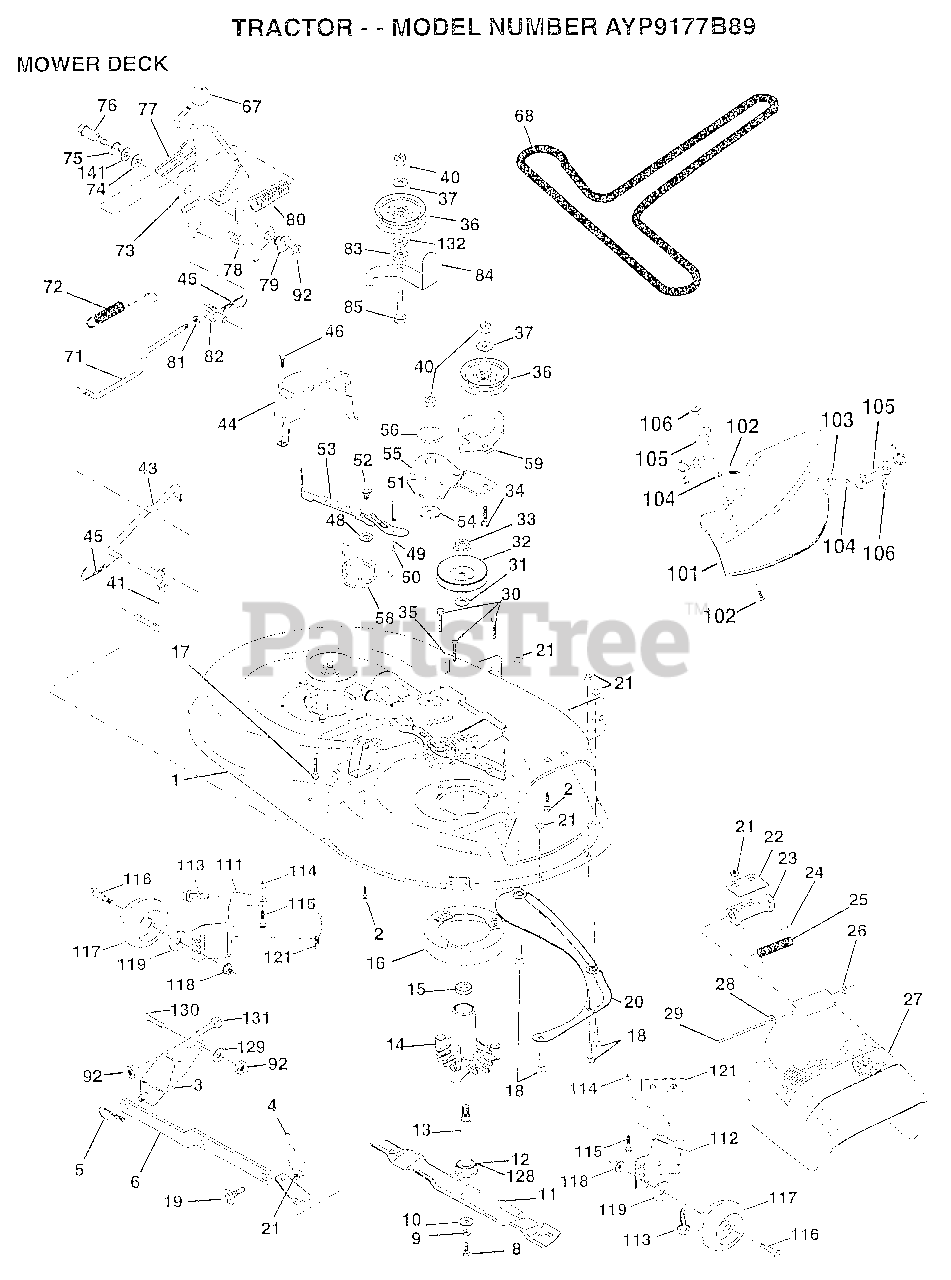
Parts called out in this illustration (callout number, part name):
1	"HOUSING ASSY.42"""
2	BOLT
3	BRKT ASM SWAY BAR
4	BRKT DECK SW BAR
8	BLADE BOLT
10	WASHER.HARD.BLADE
11	"BLADE.42"" MULCHER"
12	BEARING.BALL
14	HSG ASM MANDREL
15	BEARING
16	STRIPPER RND MWR
17	BOLT RDHD 3/8-16
18	BOLT
19	BOLT SHD 5/16-18
20	BAFFLE VORTEX 42
22	STIFFENER BRKT
23	DEFLECTOR BRKT
25	SPRING TORSION
27	DEFLECTOR.SHIELD
28	WASHER
29	HINGE ROD
30	"SCREW-THD ROLL,WA"
31	WASHER
32	PULLEY.MANDREL.42
34	BOLT
35	XMAS TREE FASTNER
36	FLAT IDLER PULLEY
37	WASHER
41	PIVOT ROD
43	ROD CLUTCH W/NIBS
44	GUARD MAND LH BLK
46	SCREW.1/4-20X5/8
48	HARD SMALL WASHER
49	ROLLER ASM-CAM
50	SHOULDER BOLT
51	LOCKNUT
52	BOLT.SHLD.5/16-18
53	BRAKE PAD ARM ASM
54	HARDENED WASHER
55	ARM-IDLER
56	SPACER RETAINER
58	SPRING TORSN BRAK
59	GUARD IDLER TUV
67	KNOB.RD.7/16-14
68	BELT.V.T-PATH
71	ROD CLUTCH 38/42
72	RETURN SPRING
73	CLUTCH ARM SECOND
74	WASHER
75	RING
76	SHOULDER BOLT
77	SPRING KEEPER
78	LEVER.ASM.CLUTCH
79	BUSHING
80	SPRING.CLUTCH.MWR
81	NUT
82	TRUNION ADJ
83	WASHER
84	"KEEPER-BELT,FIXED"
85	BOLT
92	NUT
101	"COVER.MULCH.42"""
102	SCREW
103	WASHER #10
104	LOCKWASHER
105	LATCH ASSY.BAGGER
106	WELDNUT
111	BRACKET.GWHL.LH.
112	BRACKET.GWHL.RH.
113	SCREW
116	BOLT.SHOULDER
117	WHEEL GAGE DONUT
118	LOCKNUT
119	WASHER
121	BRACKET.EXTRD.GWL
128	WASHER.FELT.
129	WASHER
130	BOLT
132	WASHER GT
141	WASHER .T
